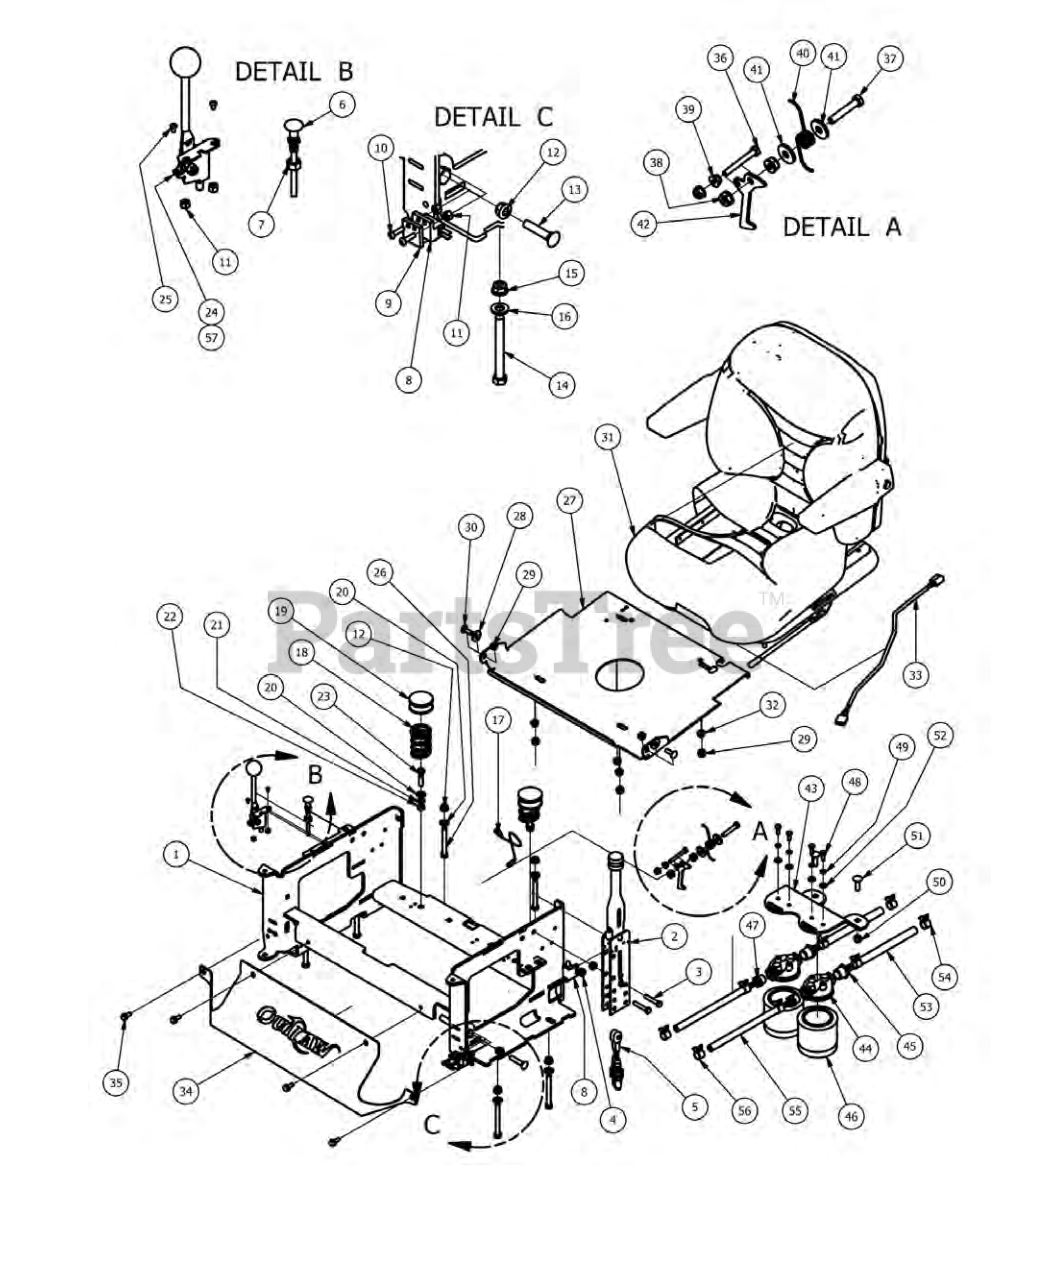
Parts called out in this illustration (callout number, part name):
1	Outlaw Seat Bracket 2012
2	Hand Brake
3	5/16" x 13/4" Hex Bolt
4	5/16-18 Nylon Flange Nut
5	Long Brake Cable
7	3/8" Fine Threaded Jam Nut
8	Safety Switch
9	Switch Block Plastic
10	10-24 x 1 BS C/S 18-8 SS
11	10-24 Nylon Insert Locknut
12	3/8" Nylock Flange Nut
13	3/8 x 1 3/4 Carriage Bolt
14	3/8-16x3-1/2 grade 5 hex bolt
15	3/8" Nylock Flange Nut
16	3/8" Flat Washer
17	Seat Cable
18	3/4 OD x 1/2 ID x 3\4 Length
19	Spring Cap Cover
20	3/8" Flat Washer
21	3/8" Lock Washer
22	3/8" Hex Nut
23	3/8" x 1 1/2" Hex Bolt
24	Throttle-All Outlaws For Vanguard Models
25	10-24 X 5/8 BS C/S 18-8 SS
26	3/8-16x3 grade 5 hex bolt
27	2006 Seat Plate
28	.360 ID Plastic Washer
29	5/16-18 Nylon Flange Nut
30	5/16" x 1" Carriage Bolt
31	2010 Outlaw Seat
32	5/16" Flange Nut
33	Seat Switch Adapter
34	Outlaw Cooler Cover
35	5/16 x 3/4 washer head type F screw
36	1/4-20 x 2 Hex Bolt
37	5/16-18 X 2 Hex C/S (GR.5)
38	5/16-18 Nylon Flange Nut
39	1/4-20 Hex Flange Nuts Zinc w/Serrations
40	Torsion Spring for Seat latch
41	.360 ID Plastic Washer
42	Seat Latch Lever
43	Outlaw Filter Bracket
44	Filter Head-Hydraulic Filter
45	Filter Head Fitting 1/2 x 1/2
46	Hydraulic filter
47	1/2" Pipe to 3/8" Barb
48	1/4" x 3/4" Hex Bolt
49	1/4" Lock Washer
50	3/8 Nylock Nut
51	3/8" x 1/4" Carriage Bolt
52	1/4" Flat Washer
53	1/2 Clear Braded Hose Priced/Foot
54	1/2 Hose Clamp
55	3/8 clear hose price per foot
56	3/8 hose clamp
57	Throttle for Kawasaki Models
